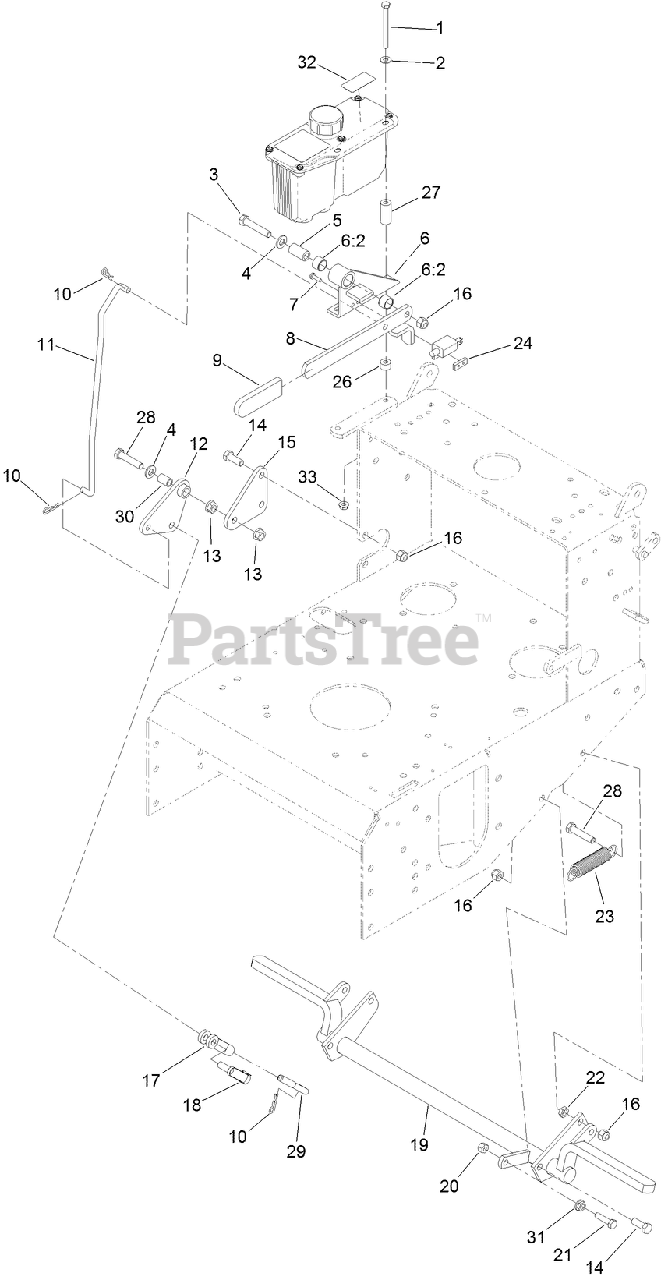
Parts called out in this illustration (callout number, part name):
1	SCREW-HH
2	WASHER-FLAT
3	SCREW-HH
4	WASHER-FLAT
5	BUSHING-PIVOT
6	BRACKET ASM
6:2	SLEEVE-BUSHING
7	SCREW-PPH
8	PARK BRAKE LEVER
9	GRIP-LEVER
10	PIN-COTTER
11	LINKAGE-UPPER
12	BELLCRANK ASM
13	NUT-HF
14	SCREW-HH
15	BELLCRANK
16	NUT-LOCK, NI
17	YOKE-LINKAGE, BRAKE
18	PIN-SPRING, CLEVIS
19	SHAFT-CROSS, BRAKE
20	NUT-LOCK, NI
21	SCREW-HH, SPECIAL
22	NUT-JAM
23	SPRING-IDLER
24	PLATE-TAPPED
26	SPACER
27	SPACER
28	SCREW-HH
29	LINKAGE-LOWER
30	BUSHING-PLASTIC
31	NUT-HF
32	DECAL-BRAKE, PARK
33	NUT-HF
